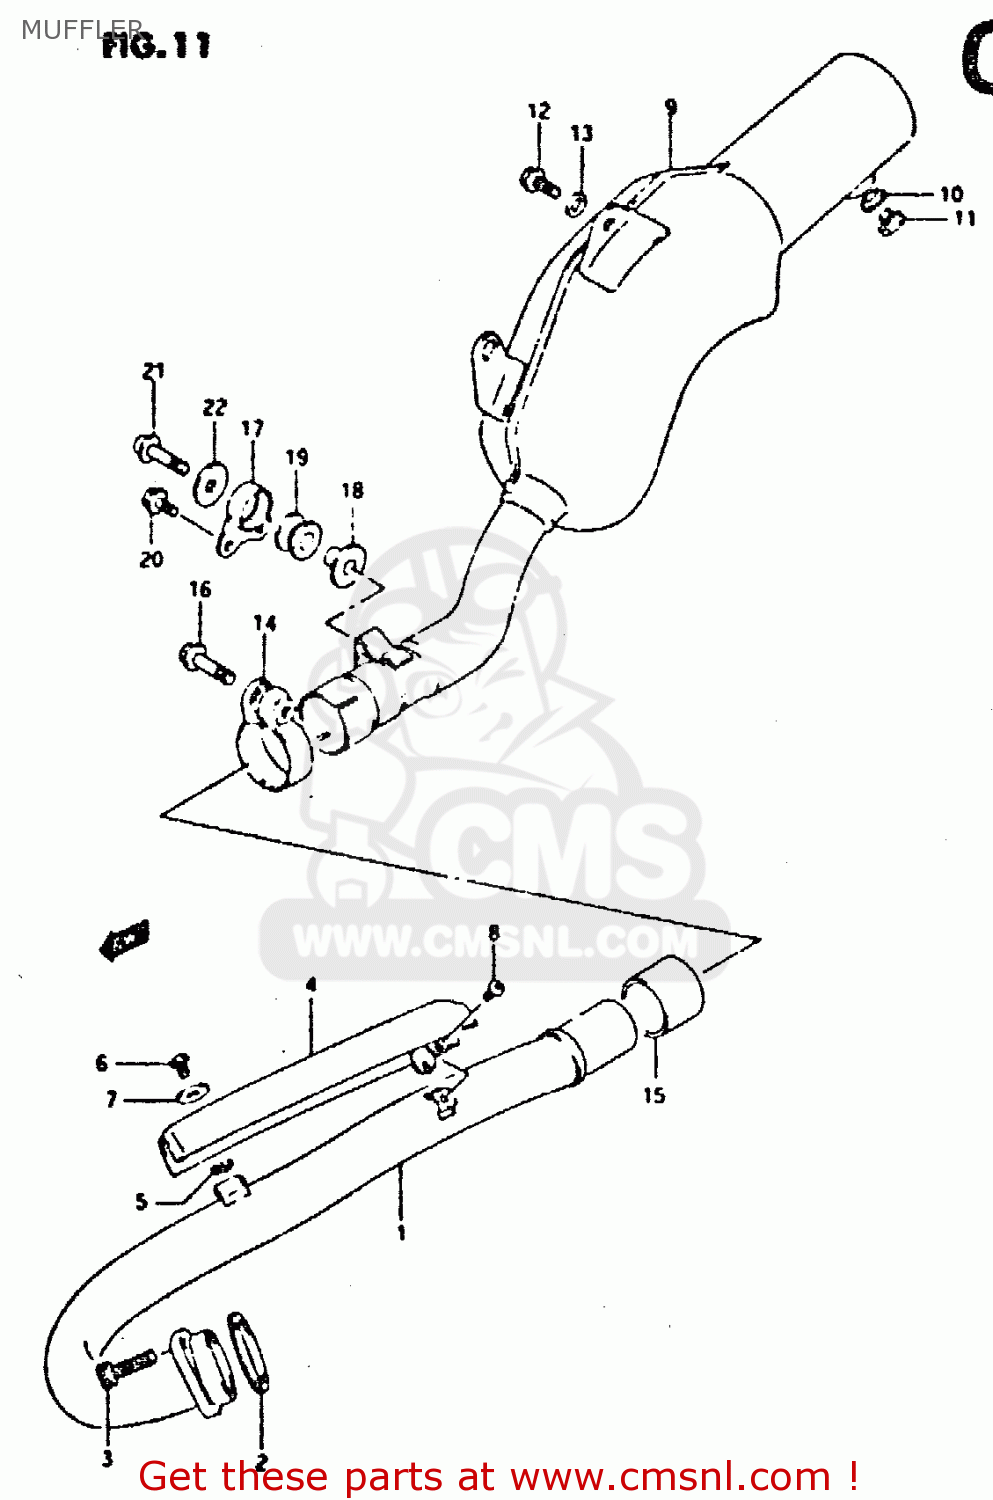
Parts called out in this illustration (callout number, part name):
1	PIPE,EXHAUST
2	GASKET,EXHAUST (NAS)
3	BOLT
4	COVER,EXHAUST PIPE
5	GASKET(5.8X13X1.4) (NAS)
6	SCREW(6X10)
7	WASHER(6.5X18X1)
8	SCREW
9	BODY,MUFFLER
10	GASKET(12.1X16.2X3.7) (NAS)
11	PLUG(12X9)
12	BOLT(8X20)
13	WASHER (8.5X19X2.3)
14	CLAMP,PREMUFFLER CONNECTOR,L
15	CONNECTOR,MUFFLER
16	BOLT
17	DAMPER,MUFFLER SUPPORT JOINT
18	SPACER(8.6X12X17.5)
19	CUSHION
20	BOLT 6X12
21	BOLT 8X35
22	WASHER (8.5X20X1.6)
